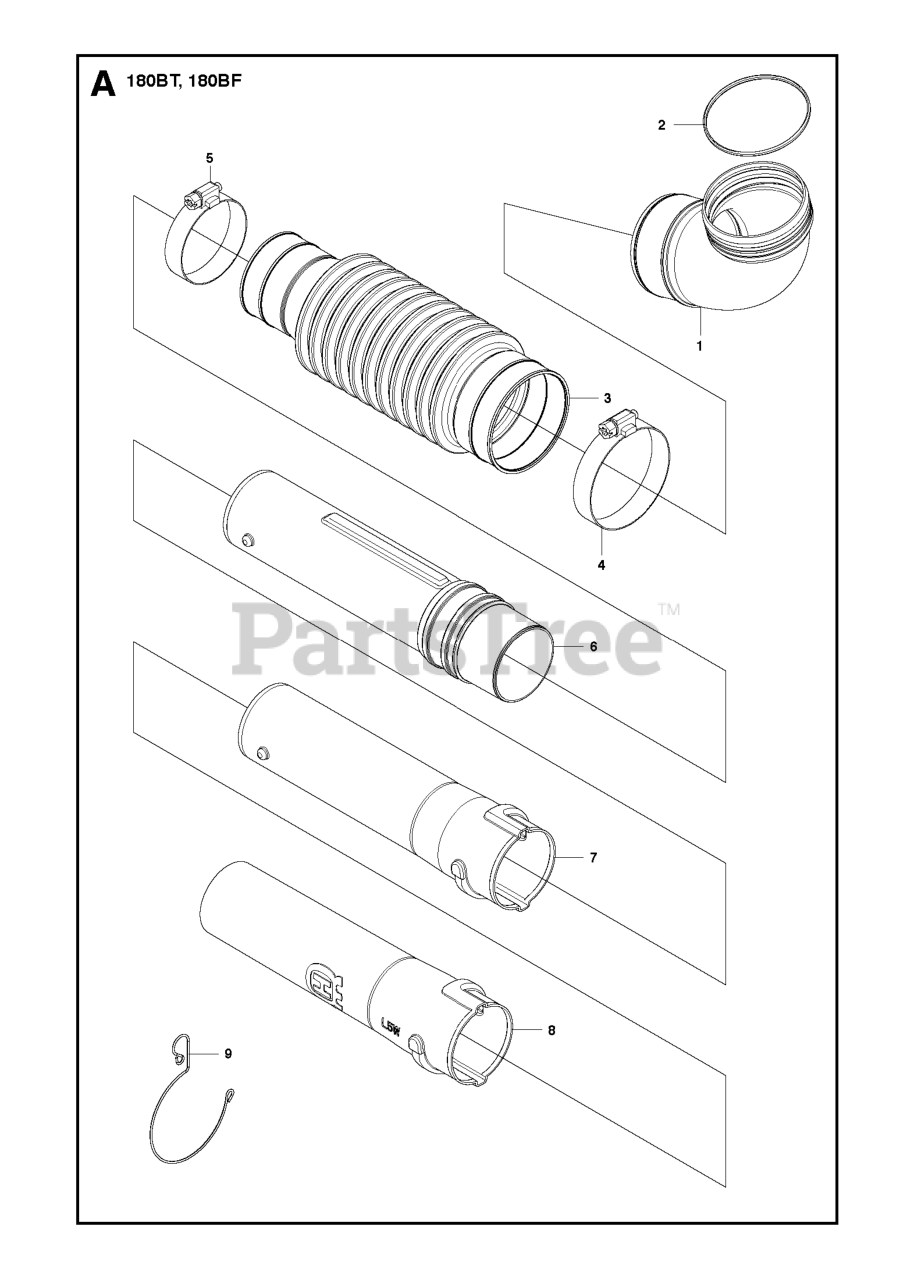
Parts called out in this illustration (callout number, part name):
4	CLAMP(F115)
5	CLAMP(F96)
6	SWIVEL JOINT
7	PIPE,STRAIGHT
